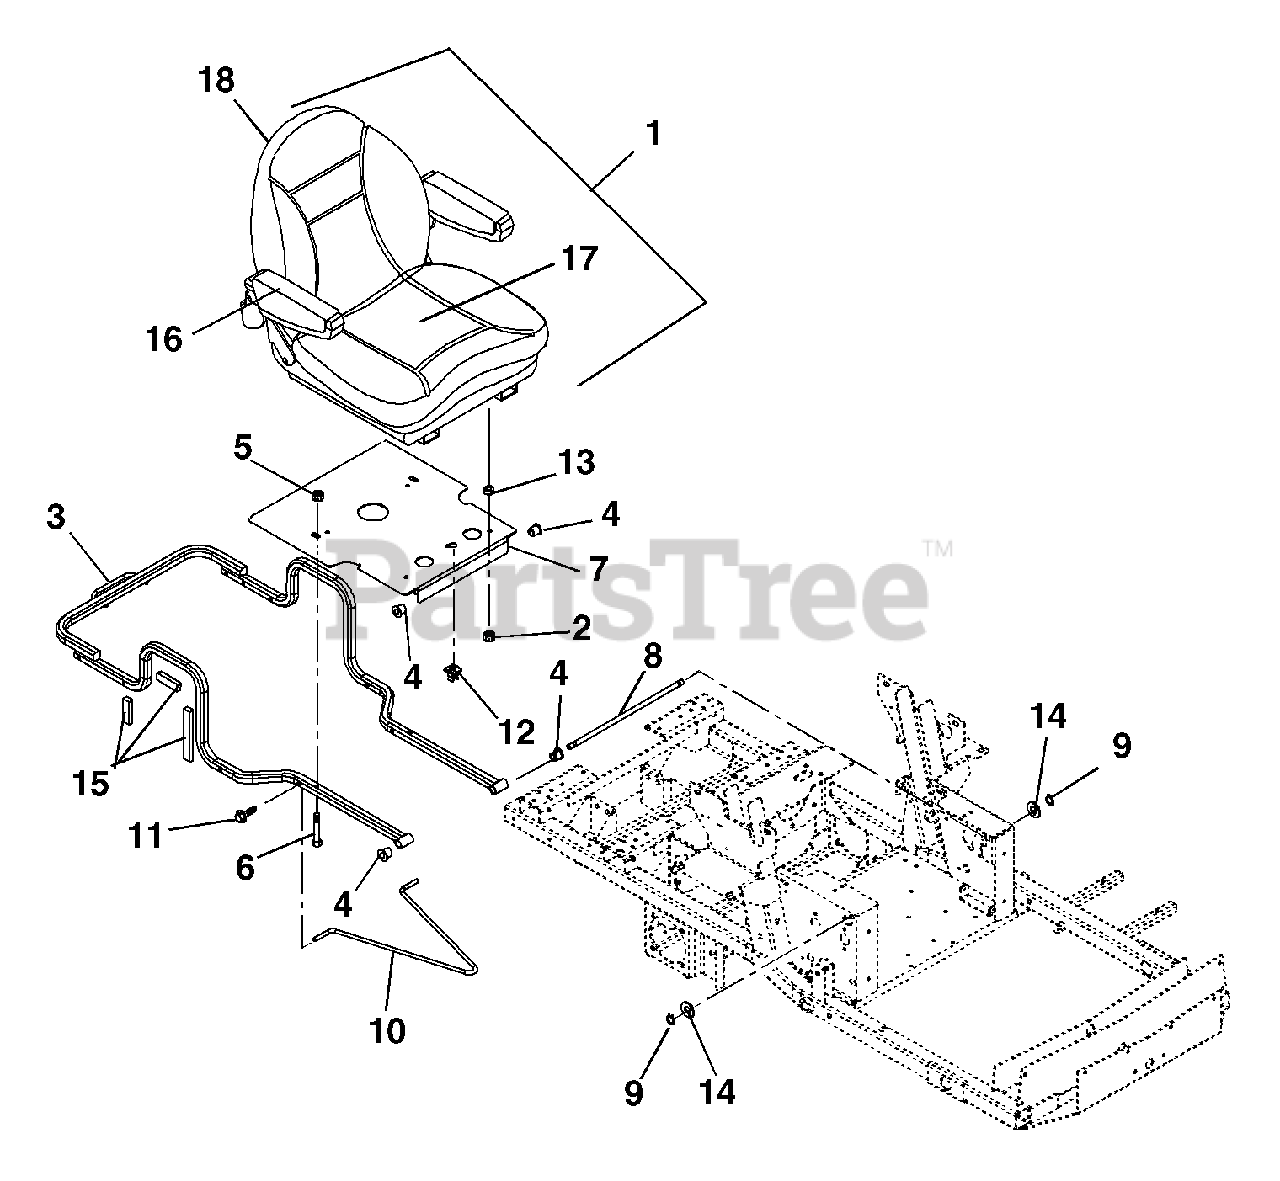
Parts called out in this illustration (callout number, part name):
1	SEAT,
2	@NUT-LK-TOP-FLG .31-18 YWZC
3	WMT, HOOD FRAME
4	BSHG-FLG .515X.750X.745X1.00NY
5	@NUT-LK-TOP-FLG .38-16 YWZC
6	BLT, .38-16X1.50 RIB NECK YWZC
7	WMT, SEAT PIVOT MOUNT
8	ROD - SEAT FRAME PIVOT
9	RG-RTNG-EXT .500X.050 (SNAP)
10	ROD, SEAT PROP
11	@SCR-TAP .25-20X.50 HWH TR YWZ
12	CLIP-.38
13	BSHG-SLV .377X.624X.235
14	@WSHR-FL-STL.531X1.06X.095YWZC
15	VHB TAPE 4941F
16	KIT,ARMREST PAD ONLY 1 PER KIT
17	KIT,SEAT CUSHION
18	KIT,BACK CUSHION
